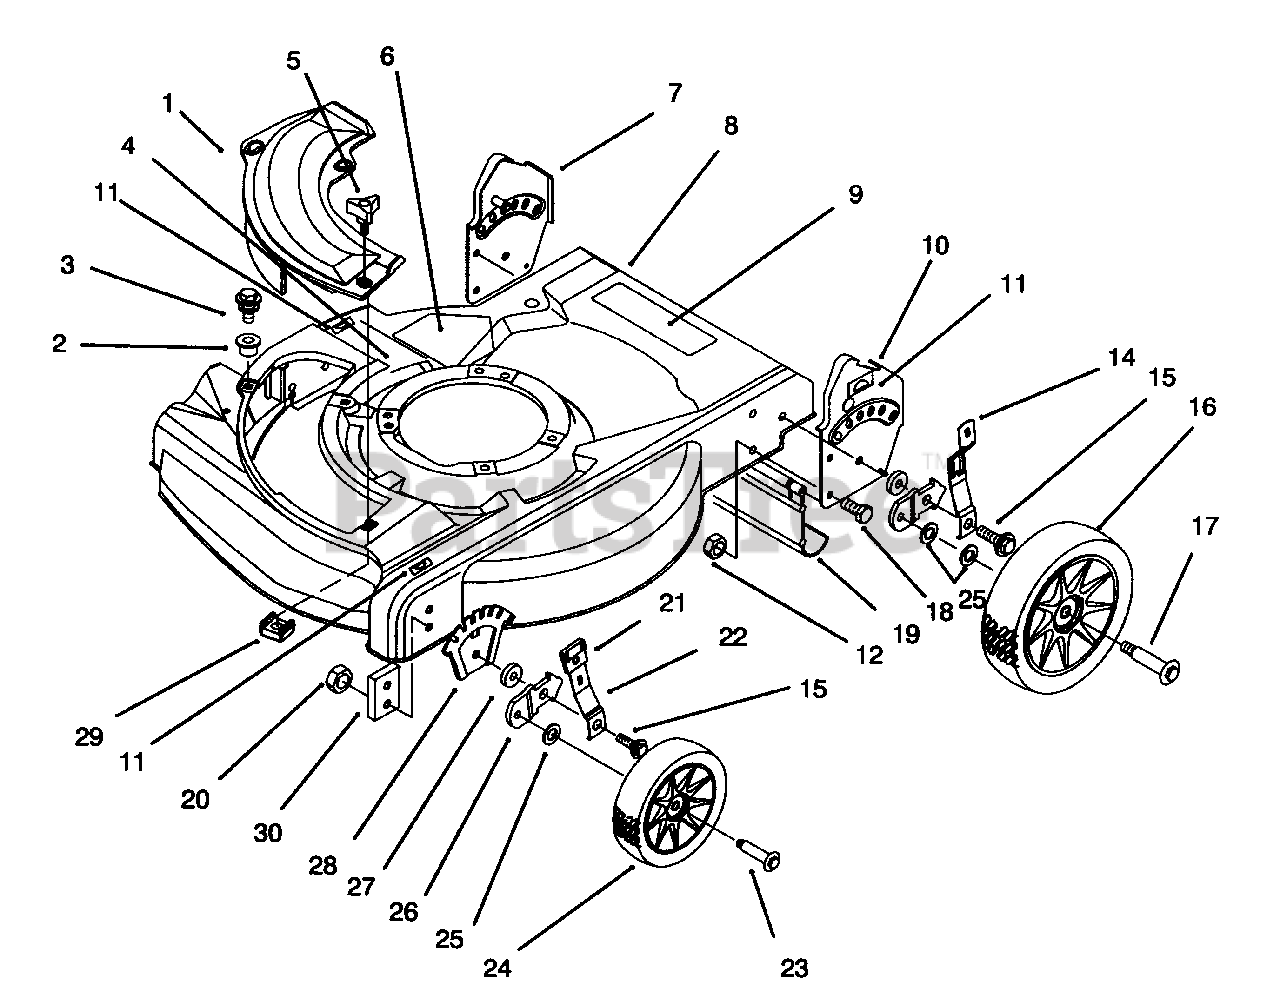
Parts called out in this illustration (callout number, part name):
1	Cover Plate Mulch
2	Grommet-Plastic
3	Screw-Thread Forming
4	Decal-Danger (English)
5	Knob
6	Decal-Danger (English)
7	Handle Bracket Ass'y-R.H.
8	Housing & Baffle Ass'y (Incl. ref. #2-6, 9, 11 & 29)
9	Decal-Danger (English)
10	Handle Bracket Ass'y-L.H.
11	Decal-H.O.C. L.H.
14	Spring Arm Assembly
15	Bolt-Shoulder
16	Wheel Ass'y-8"
17	Bolt-Wheel
18	Screw-Hex Head
19	Shield-Trailing
21	Knob-H.O.C. Lever
22	Spring Arm Assembly, Front
23	Bolt-Wheel
24	Wheel Ass'y-6"
25	Washer-Wheel Bolt
26	Bracket-H.O.C.
28	Plate-H.O.C. Front
29	Nut-Cage
30	Plate-Baffle
